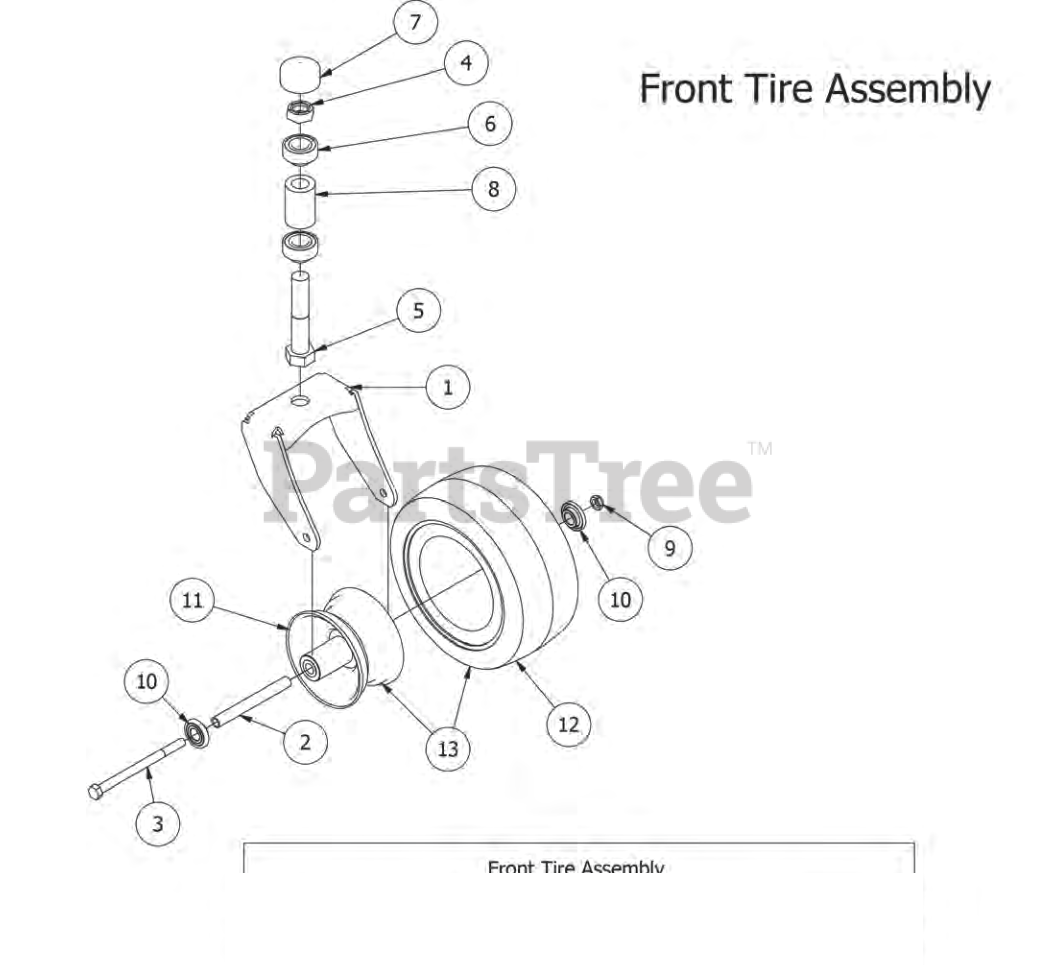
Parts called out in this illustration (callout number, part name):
1	Front Fork MZ
2	Front Wheel Spanner
3	1/2 x 7 Hex Bolt Grade 5
4	1" Fine Thread 1/2 Nut
5	1-14 x 5 Hex Bolt Grade 8 Zinc Yellow
6	Caster Bearing -MZ, 2009 & up
7	Rubber Bearing Cap
8	MZ Caster Bearing Spacer
9	1/2" Nylcock Nut (1/2 Jam)
10	Wheel Bearing
11	Front wheel
12	11x4.00-5 Tire Only
13	11x6-5 Front Tire & Wheel Assembly
